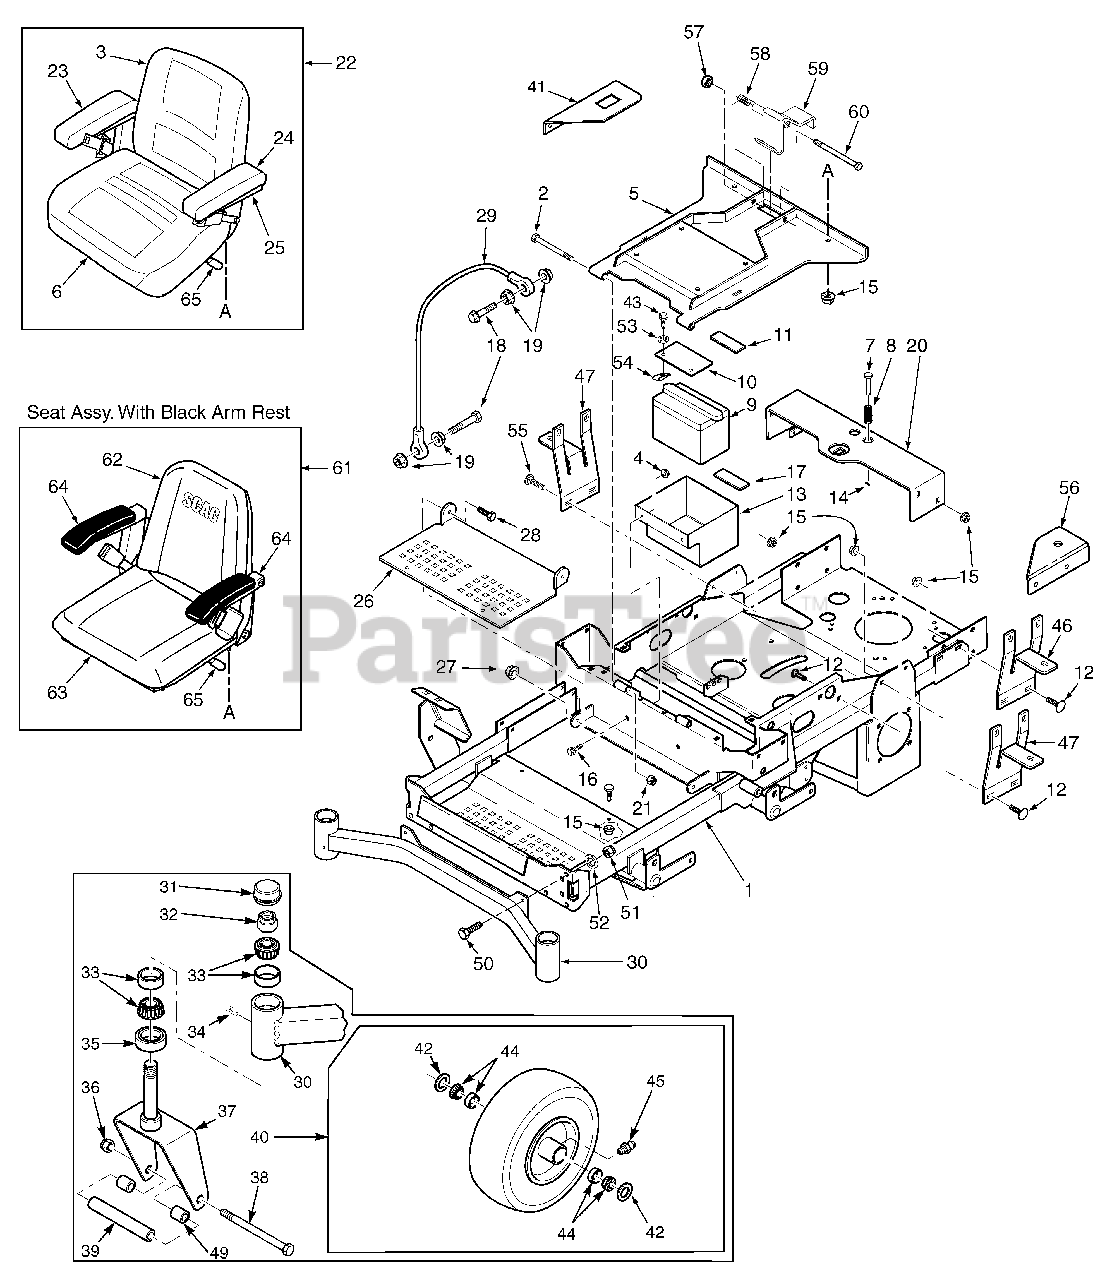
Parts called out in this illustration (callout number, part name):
1	Main Frame Assembly w/decals
2	Bolt, Hex Head 5/16-18 x 3-3/4"
3	Cushion, Back
4	Nut, Serr. Flange 3/8-16
5	Plate, Seat Mounting w/decals
6	Cushion, Lower Seat
7	Pin Retainer, Spring
8	Spring
9	Battery
10	Battery Cover
11	Battery Hold Down Pad
12	Bolt, Carr. 5/16-18 x 3/4"
13	Battery Box
14	Roll Pin, Spring 5/32 x 3/4"
15	Nut, Serr. Flange 5/16-18
16	Bolt, Hex Head 3/8-16 x 1"
17	Pad, Rubber
18	Bolt, Hex Head 1/4-20 x 1-1/4"
19	Nut, Serr. Flange 1/4-20
20	Seat Base Support
21	Nut, Elastic Stop 5/16-18
22	Seat Assembly w/ adjustment rails
23	Arm Pad, RH
24	Arm Pad, LH
25	Channel, Armrest
26	Footplate
27	Nut, Elastic Stop 3/8-16
28	Bolt, Hex Head 3/8-16 x 1"
29	Cable, Seat Stop
30	Weldment, Caster Support
31	Cap, Grease
32	Nut, Elastic Stop 1.0-14
33	Bearing Set
34	Plug, 1/4-28
35	Seal, 2.0" OD x 1.625" ID
36	Nut, Elastic Stop 1/2-13
37	Yoke, Front Caster Wheel
38	Bolt, Hex Head 1/2-13 x 7-1/2"
39	Sleeve
40	Caster Wheel Assembly
41	Bracket, Hour Meter
43	Bolt, Hex Head 3/8-16 x 1-1/4"
44	Roller Bearing
45	Fitting, Grease
46	Mounting Bracket, Oil Tank
47	Mounting Bracket, Fuel Tank
48	Seat Pan
49	Spacer, Caster Wheel
50	Bolt, Hex Head 7/16-14 x 1-1/4"
51	Nut, Elastic Stop 7/16-14
52	Lockwasher, 7/16"
53	Lock Washer. 3/8 Spring
54	U-Nut, 3/8-16
55	Bolt, Carriage 5/16-18 x 1"
56	Bracket, Fuel Valve
57	Lock Nut, 3/8-16 Center Lock
58	Spring, Seat Latch
59	Seat Latch Weldment
60	Bolt, Hex Head 3/8-16 x 6"
61	Seat Assembly w/ adj. rails
62	Cushion, Back
63	Cushion, Lower Seat
64	Arm rest Kit
65	Seat Adjustment Track Set
